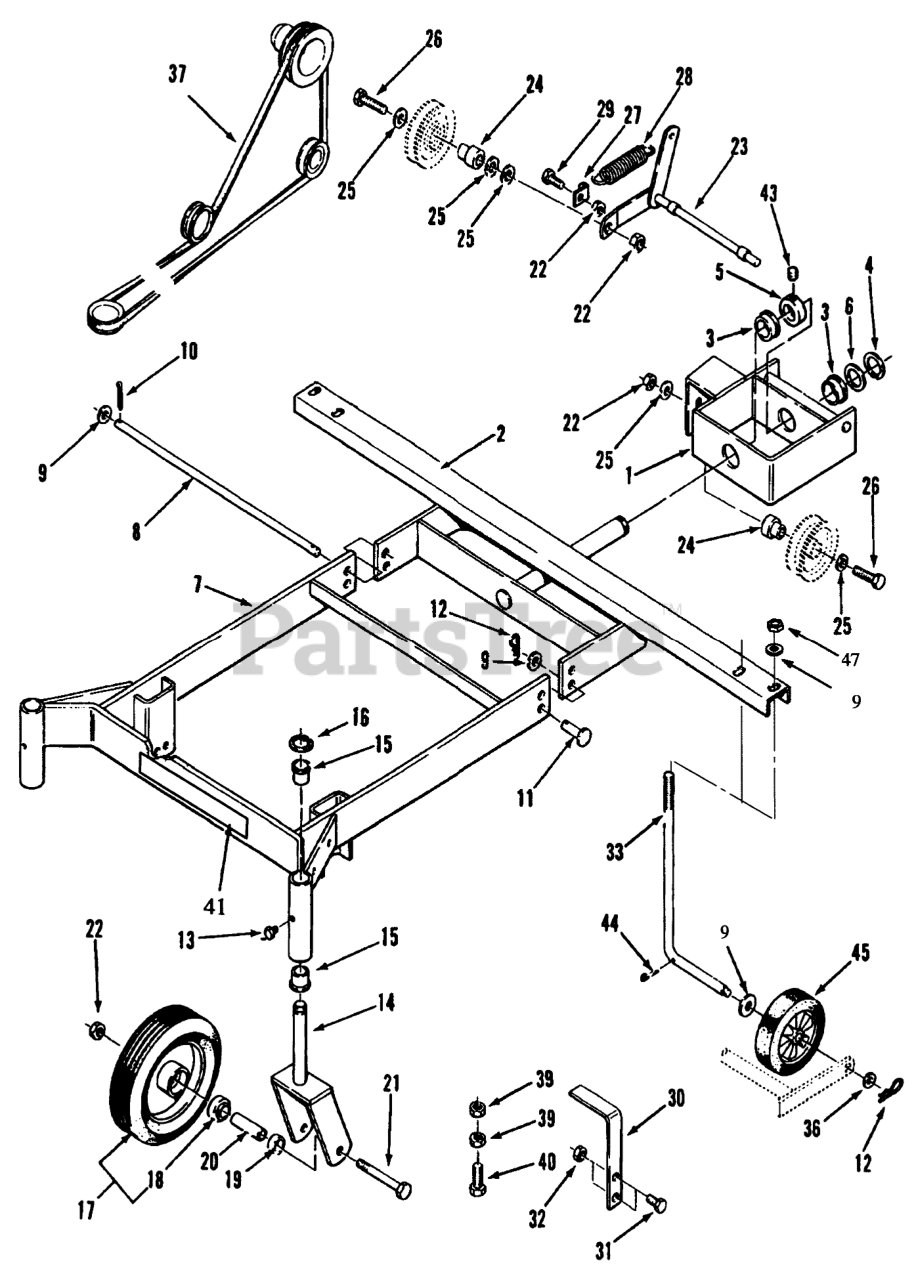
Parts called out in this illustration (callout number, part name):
1	ASS'Y-HITCH FRAME R
2	ASSY PIVOT FRAME R
3	BUSHING
4	RING-RETAINING
5	Collar
6	Washer
7	ASSY FRAME R
8	PivotRod
9	WASHER-FLAT
10	PIN-COTTER
11	Pin-Clevis
12	PIN-HAIR
13	FITTING-GREASE
14	ASSY SWIVEL CASTE R
15	BUSHING
16	Ring-Snap
17	Wheel Assembly (incl. Ref. #18)
18	Bearing-Ball
19	SPACER
20	SPACER
21	SCREW-HH
22	NUT-HEX
23	ASSY BELT ADJ R
24	SPACER
25	WASHER-FLAT
26	SCREW-HH
27	CLIP - SPRING
28	SPRING-EXTENSION
29	SCREW-HH
30	HANDLE-EXTENSION R
31	SCREW-HH
32	NUT-LOCK
33	ROD HANGER R
36	WASHER-FLAT
37	BELT MOWER DRIVE
39	NUT-HEX, JAM
40	SCREW-HH
41	DECAL-ATTACHMENT
43	Screw-Set
44	PIN-COTTER
45	WHEEL ASM
47	NUT-LOCK, NI
